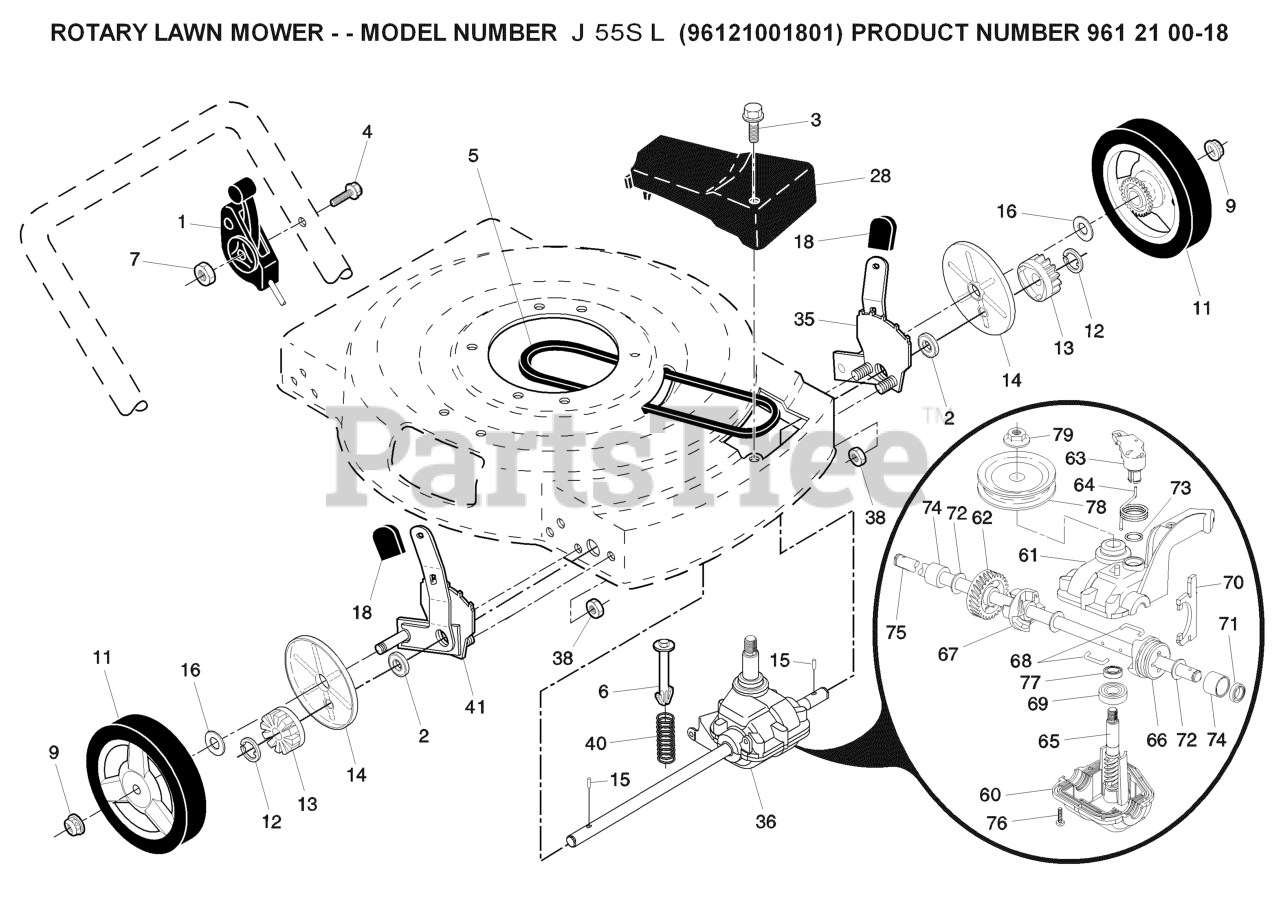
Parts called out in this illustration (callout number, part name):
1	DRIVE CONTROL 59.8 FWGD
2	BEARING
3	Screw, Tapping, Pan Head #10-24 x 2-3/4
4	SCREW.PAN.HEAD
5	BELT THERM .32
6	SPRING RETAINER
7	NUT.HEX.FLANGE.1/4
9	NUT.HEX.FLANGE.3/8-16.LO(3 2)
11	WHEEL.8X1.75.H3SPK.RAD3.GY.BU3
12	E-RING 7/16 RE
13	PINION.14.TEETH.FGD
14	COVER.DUST.WHEEL
15	PAWL, DRIVE
16	WASHER FLUT
18	SELECTOR KNOB
28	Drive Cover
35	WHEEL ADJ KIT LH
36	TRANSMISSION.22.FGD/W/PULLEY
38	LOCKNUT.NYLOC.1/4-20
40	SPRING.EXTENSION
41	WHEEL ADJ KIT RH
60	LOWER CASE
61	UPPER CASE
62	GEAR.27.TEETH.WALK.MOWER
63	LEVER, CLUTCH
64	SPRING, RETURN
65	SHAFT.INPUT.WORM.GEAR(13155)
66	DOG, MOVABLE (11032)
67	DOG, FIXED GT11031
68	WIRE, FORMED (15966)
70	FORK, SHIFT
71	SEAL.OUTPUT.SHAFT
73	SEAL, CASE O-RING
75	SHAFT OUTPUT (12260 NOW 12663)
77	SEAL INPUT SHAFT
78	FLANGE.PULLEY.33027(GENERAL.TR
79	NUT.WITH.FLAT.BROKE
